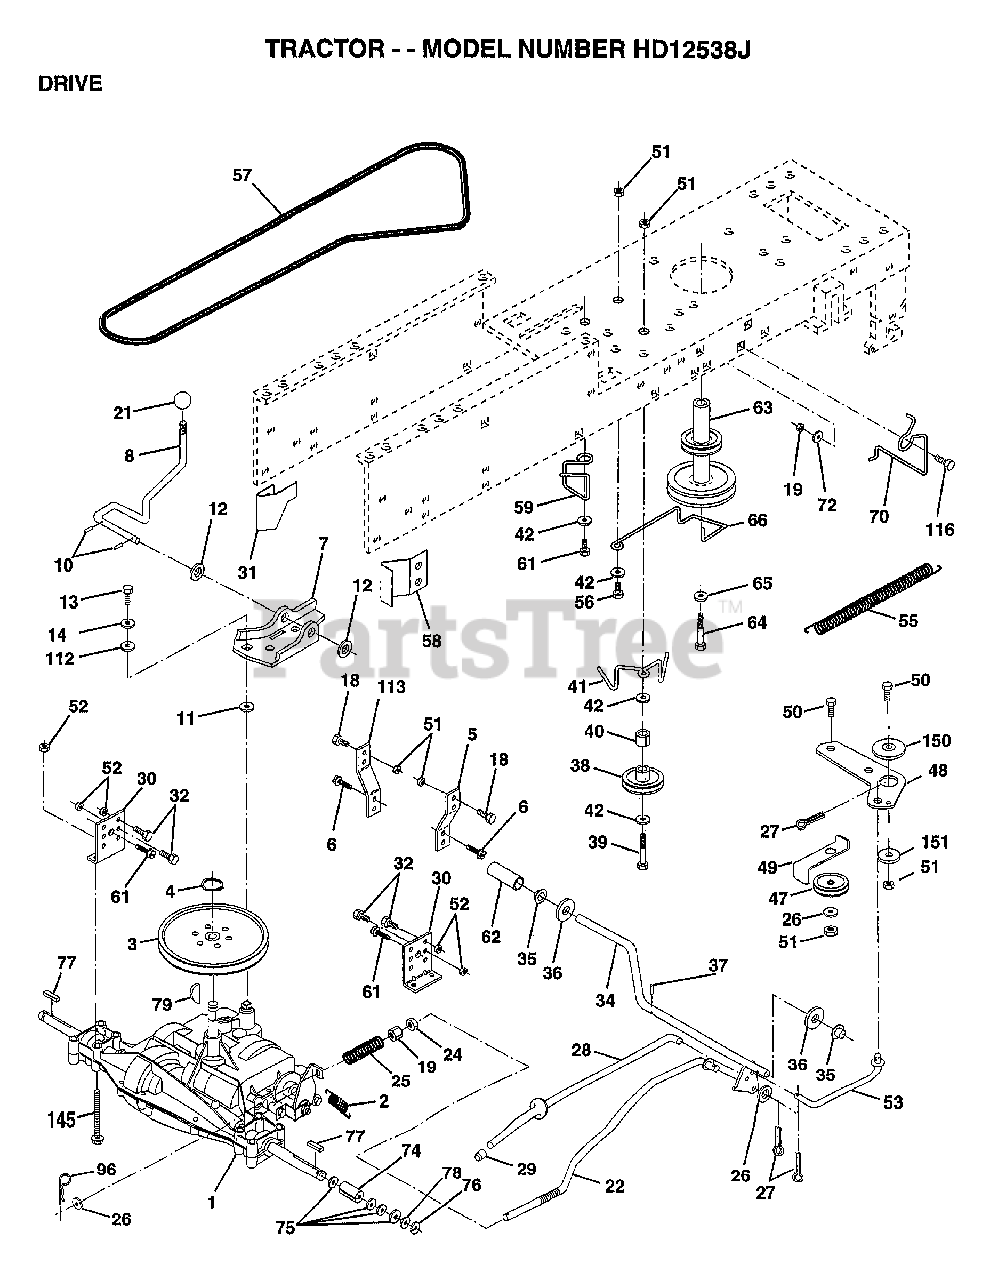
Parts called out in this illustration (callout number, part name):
2	Spring Return Brake -T/a Zinc
3	Pulley Transaxle Alum
4	Ring Retainer # 5100-62
5	Strap Pnt Torque 30 Deg Blk
6	Screw Thdrol 5/16-18 X 3/4 Tyt
6	Rod Shifter Blk
7	Bracket T/A Saddle Shift
10	Pin Cotter 1/8 1 Cad
11	Washer Plate Shf 388 Sq Hole
12	Washer 15/32 X 3/4 X 16ga
13	Bolt 1/4-28unf Gr8 w/Patch
14	Washer Lock Hvy Helical 1/4
16	Bolt Fin Flex 3/8-16 Unc x 1 Gr. 5
19	Nut Lock 3/8-16 Unc
21	Knob Rd 1/2-13 Plstc Thds Blk
22	Rod Brake Lt
24	Nut Hex Jam 3/8-16 Unc
25	Spring Rod Brake 2 00 Zinc
26	Washer 13/32 X 13/16 X 16 Ga
27	Pin Cotter 1/8 X 3/4 Cad
28	Rod Brake Parking Lt/Yt
29	Cap Parking Brake Red
30	Bracket Transmission
32	Bolt Fin Flex 5/16-18 x 3/4
33	Pulley Idler Flat
34	Shaft Asm Pedal Foot
35	Bearing Nylon Blk 629 Id
36	Washer 21/32 1 X 16 Ga
37	Pin Roll 3/16 X 1"
39	Bolt Fin Flex 3/8-16unc X 2-3/4
40	Spacer Split 395 X 59 Bzp
41	Keeper Belt Idler
42	Washer 13/32 X 13/16 12 Ga
43	Bellcrank Clutch Grnd Drv STL
47	Pulley Idler V Groove Plastic
49	Retainer Belt Style Spring
50	Bolt Flex 3/8-16unc 1-1/2
51	Nut Crownlock 3/8-16 Unc
52	Nut Lock 5/16-18 Unc
53	Link Clutch 7 66
55	Sring Return Clutch 6 75
56	Bolt Fin Flex 3/8-16unc X 1-1/4
57	V-belt Ground Drive
59	Retainer Belt Chassis Lh Zinc
61	Screw Thdrol 3/8-16x3/4 Ty-tt
62	Cover Pedal Blk Std
63	Pulley Engine
64	Bolt Finhex 7/16-20 x 4 g5
65	Washer Lock Hvy Hlcl Spr 7/16
66	Keeper Belt Engine Fool Proof
70	Guide Belt Dr Mower Rh
72	Washer 13/32 1-1/4 X 12 Ga
74	Spacer Axle
75	Washer 25/32 X 1 1/4 X 16 Ga
76	Ring E #5133-75
77	Key Square 2 0 X 1845/ 1865
78	Washer 25/32 X 1 5/8 X 16ga
79	Key Woodruff #9 3/16 X 3/4
96	Retainer Spring 1"
112	Washer 9/32 X 3/4 X 10 Ga
113	Strap Torque Lh Lt
116	Bolt Rdhd Sqnk 3/8-16 x 1.25
145	Bolt Hex FLGHD 5/16-18 Gr.5
150	Bushing Bellcrank
151	Washer 13/32 x 2 x 10 Ga.
